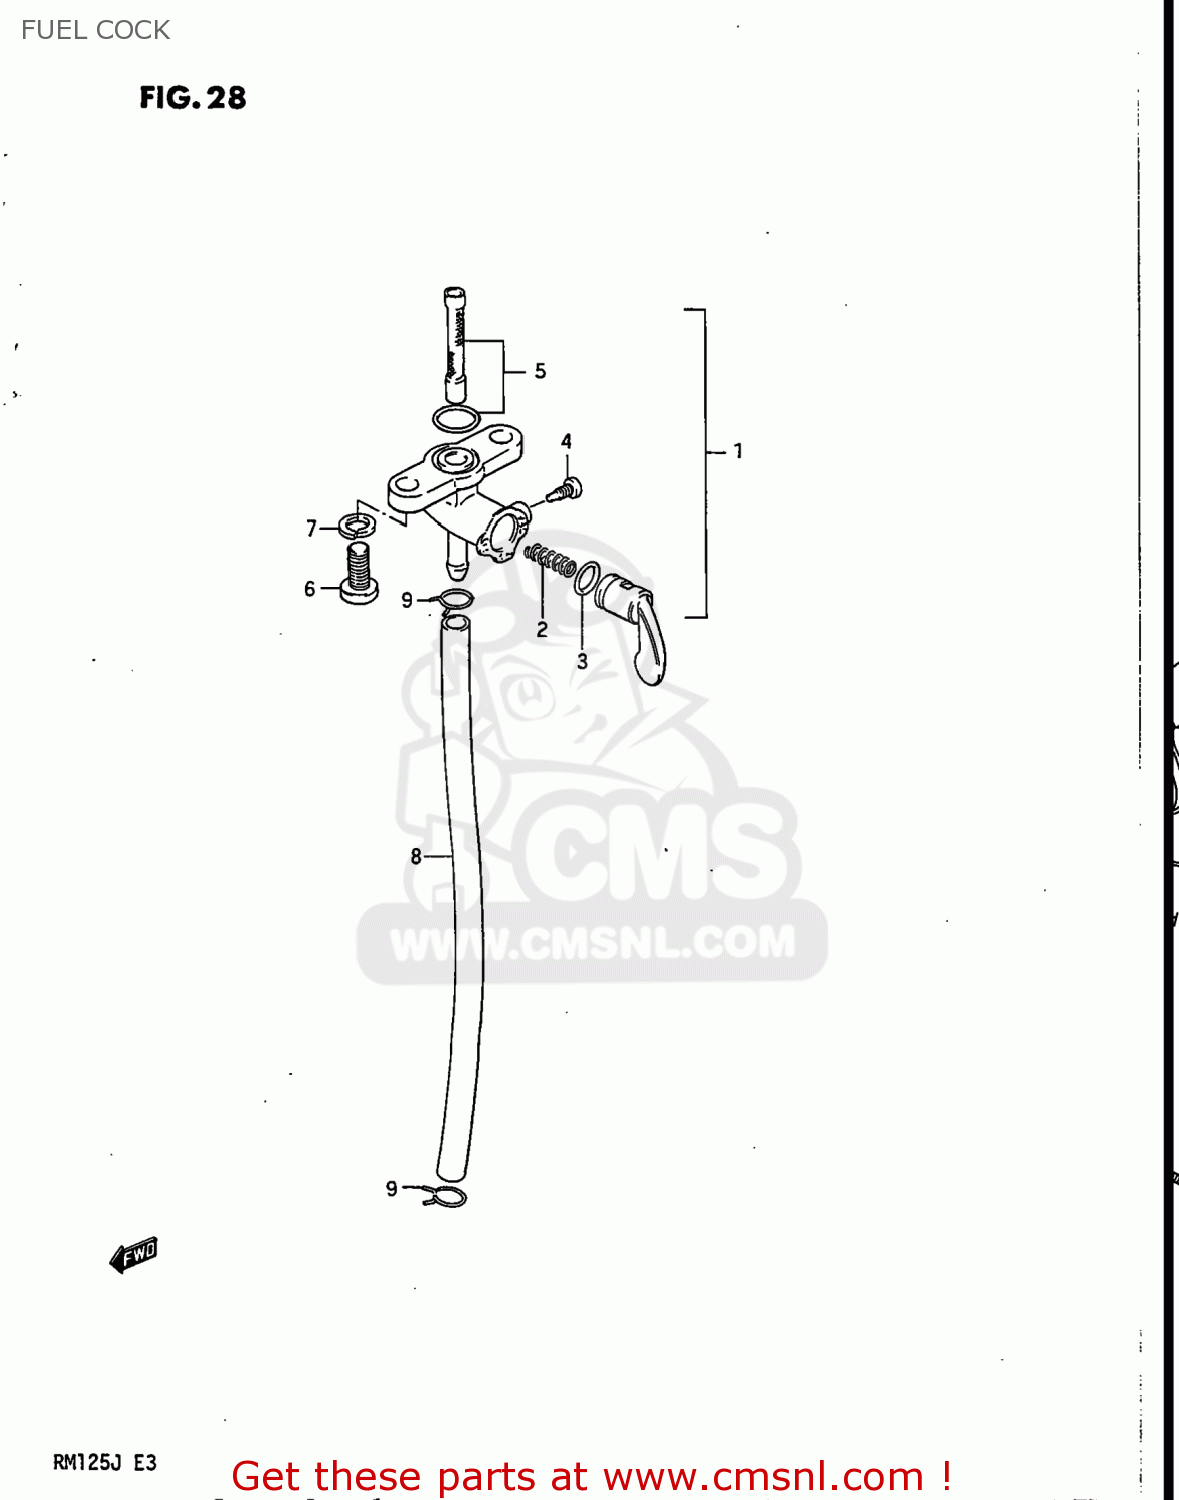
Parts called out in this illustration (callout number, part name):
1	COCK ASSY,FUEL
2	SPRING,FUEL COCK VALUE
3	O RING,LEVER
4	SCREW
5	FILTER SET FUEL
6	SCREW
7	WASHER,LOCK
8	HOSE
9	CLIP
